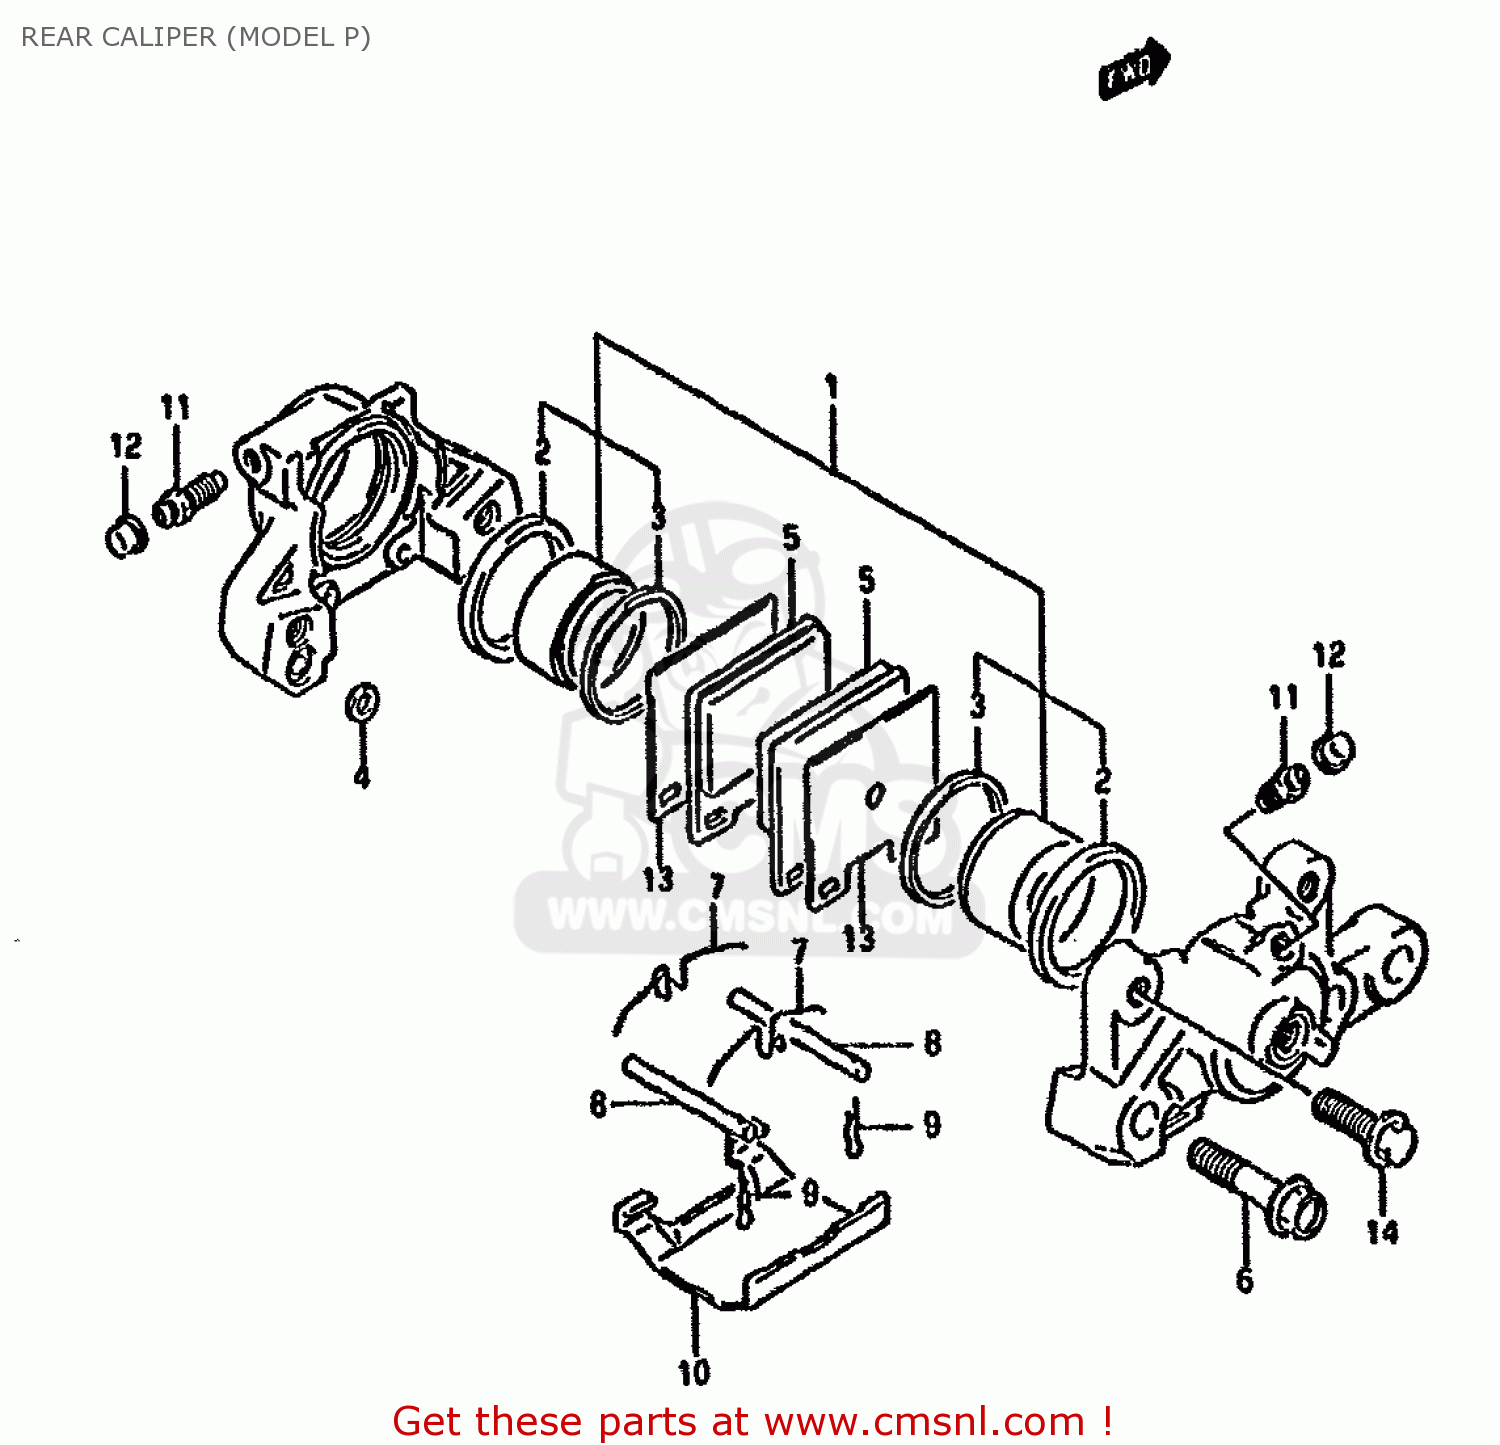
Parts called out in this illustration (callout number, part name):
1	PISTON SET
2	SEAL,PISTON
3	SEAL,WIPER
4	SEAL,JOINT
5	PAD,BRAKE
6	BOLT,HOUSING
7	SPRING
8	PIN,PAD
9	CLIP,PAD PIN
10	COVER
11	BLEEDER
12	CAP,BREATHER
13	SHIM,PAD
14	BOLT
